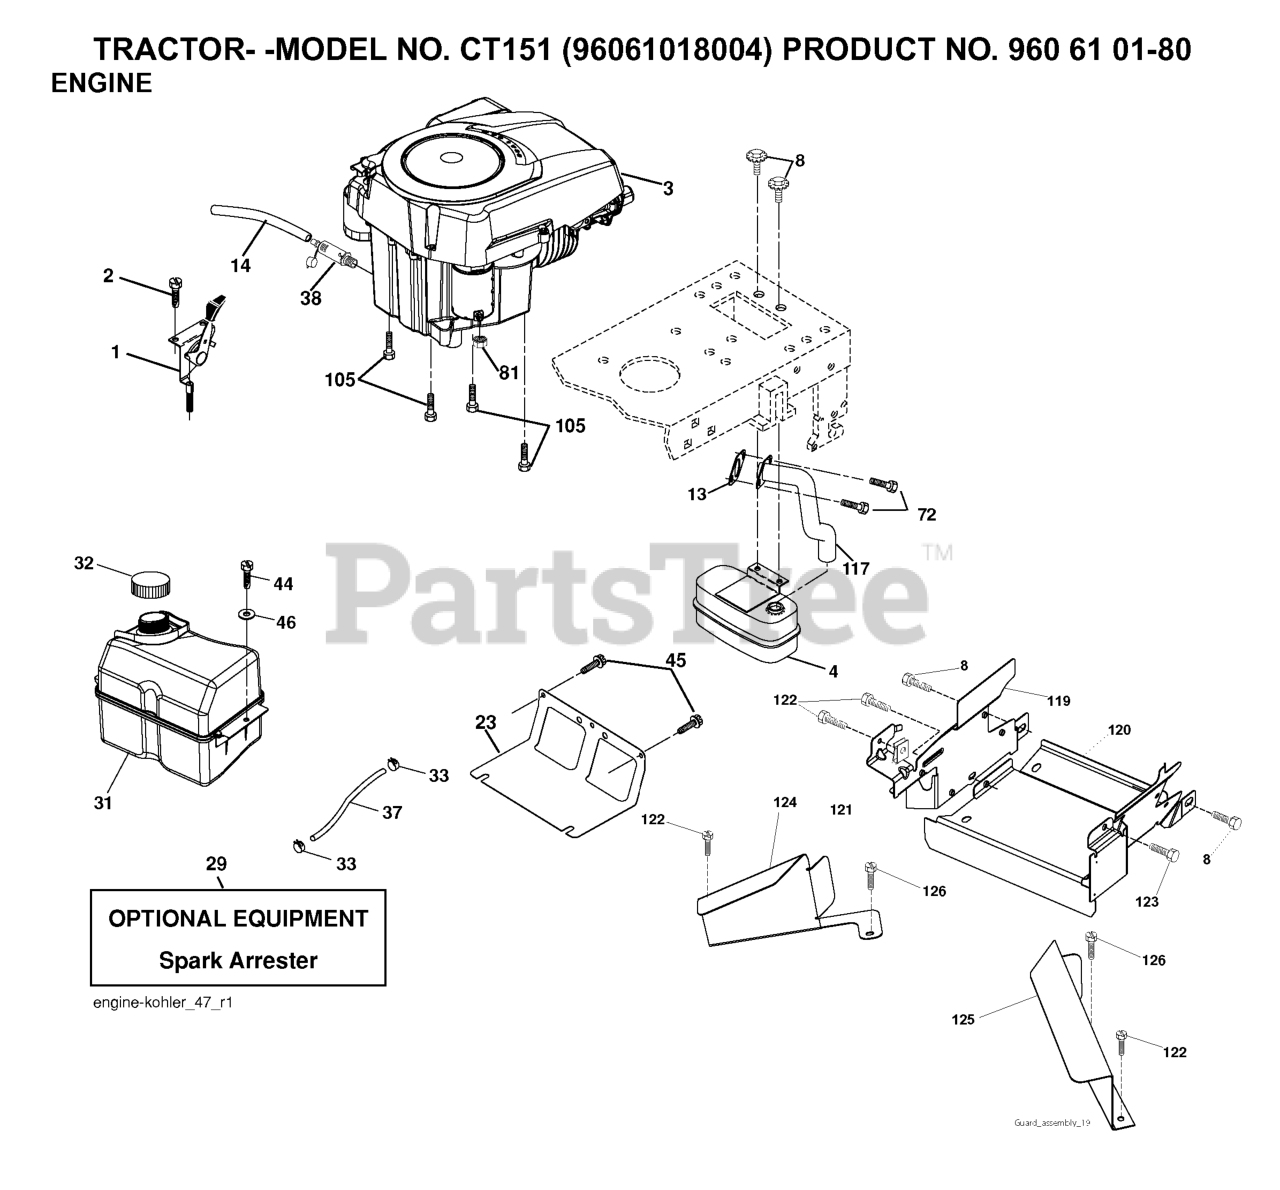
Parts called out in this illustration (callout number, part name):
1	CONTROL.TH/CK.C.
2	SCREW
4	MUFFLER.SINGLE.CYL.KOHL/B&S
8	BOLT.5/16-18UNCX3/4 W/SEMS.BLK
13	GASKET.EXHAUST.KOHLER
14	TUBE, DRAIN OIL ASM.
23	SHIELD.BROWNING.DBR.GUARD
29	KIT.SPARK ARRESTOR 794945 B&S
31	RP TANK FUEL FRT 1.5 GAL
32	FUEL CAP
33	HOSE CLAMP
37	LINE.FUEL.20
38	PLUG DRAIN OIL EASY
44	SCREW HEXWSHR 1/4-20X3/4
45	SCREW, 3/8-16X3/4
72	SCREW.SOCKET HD.5/16-1
81	NUT
105	SCREW 3/8-16X1
117	RP.TUBE.EXHAUST.KOHL.COURAGE
119	LENKRAD
120	GUARD 532199767
122	SCREW.1/4-20X5/8
123	SCREW, 5/16-18 X 1/2
126	SCREW
